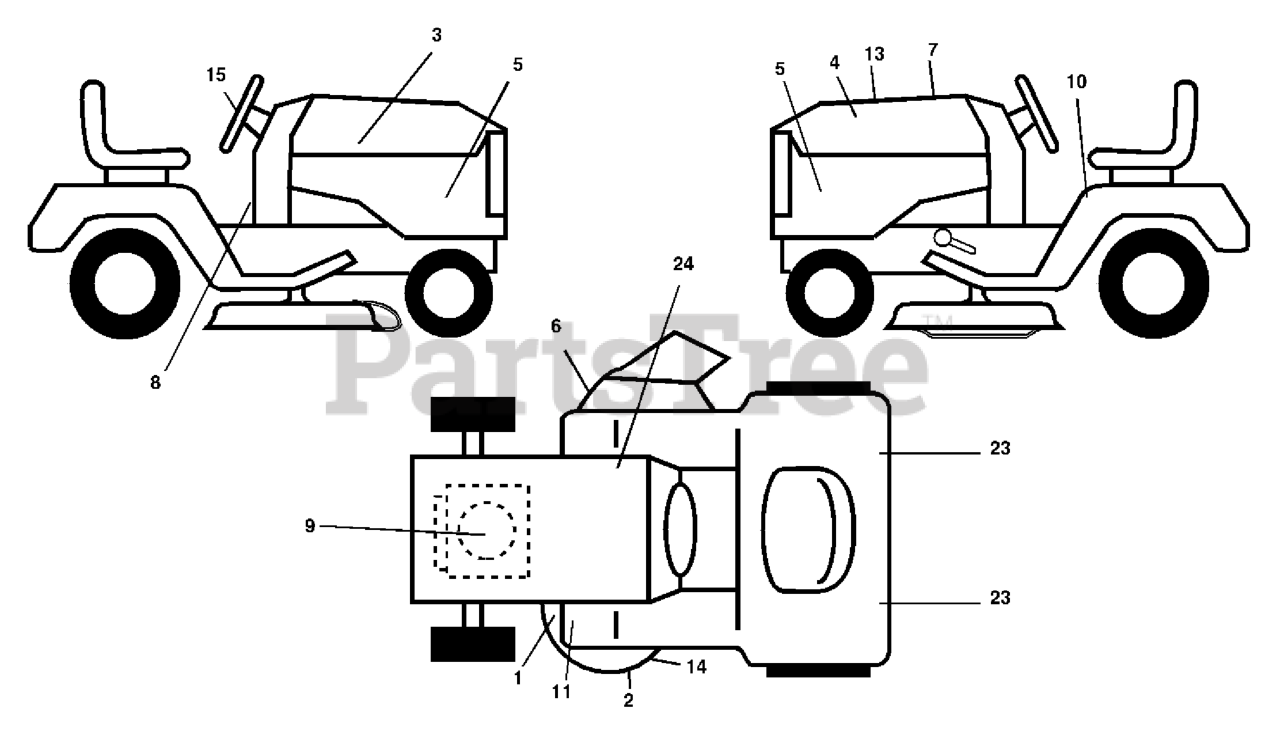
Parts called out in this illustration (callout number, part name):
1	DECAL CLUTCH/BRAKE
2	DECAL, MOWER HEAVY DUTY
5	DECAL, GTH2548
6	DECAL.WARN.KEEP.HAND.AWAY
7	DECAL HOOD CUST. RESP.
8	DECAL.SADDLE.OPERATOR
10	DECAL FENDER DANGER
11	DECAL, FOOTREST
13	DECAL, GTH2548
14	DECAL V-BELT SCHEMATIC
15	DECAL.STEERING.HUSQ.BLUE
23	REFLECTOR-TAIL YT
24	DECAL BTRY SYMBOLS
